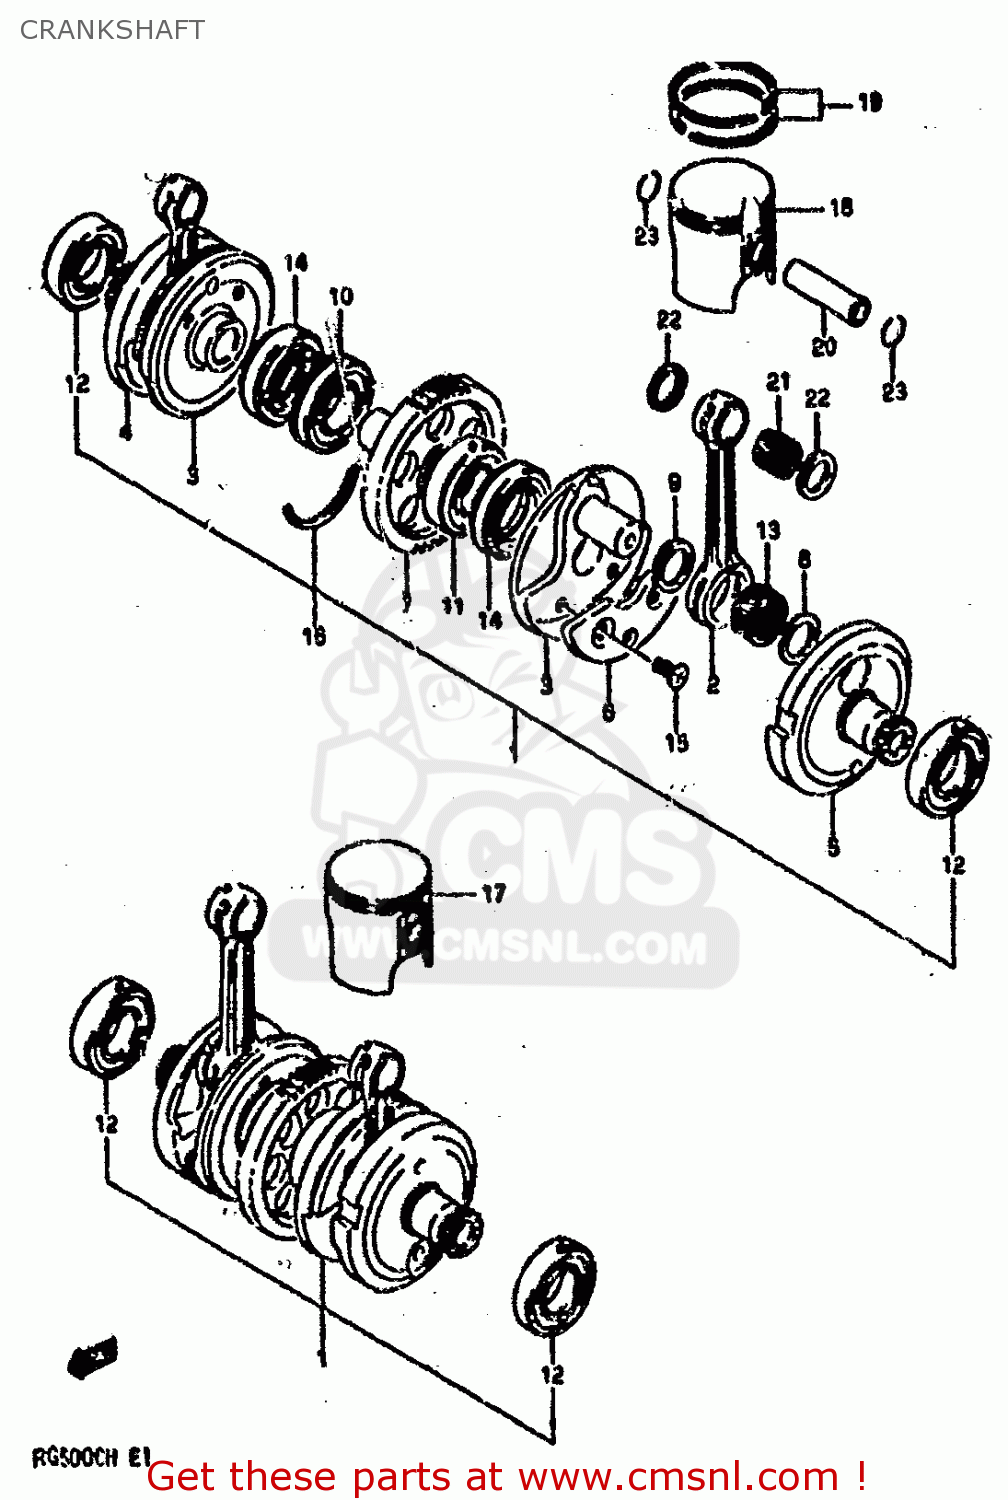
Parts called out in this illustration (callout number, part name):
1	CRANKSHAFT ASSY
2	CONNECTING ROD
3	CRANKSHAFT,INNER
4	CRANKSHAFT, OUTER NO. 1
5	CRANKSHAFT, OUTER NO. 2
6	BALANCER, CRANKSHAFT
7	GEAR, PILOT DRIVE
8	WASHER(22X27.5X1)
9	WASHER
10	BEARING
11	BEARING
12	BEARING(25X52X15)
13	BEARING
14	SEAL,OIL(32X52X8.4)
15	SCREW
16	C RING
17	PISTON,FR
18	PISTON,RR
19	RING SET,PISTON
20	PIN,PISTON
21	BEARING 14X18X19.8
22	WASHER
23	RING,SNAP 14MM
